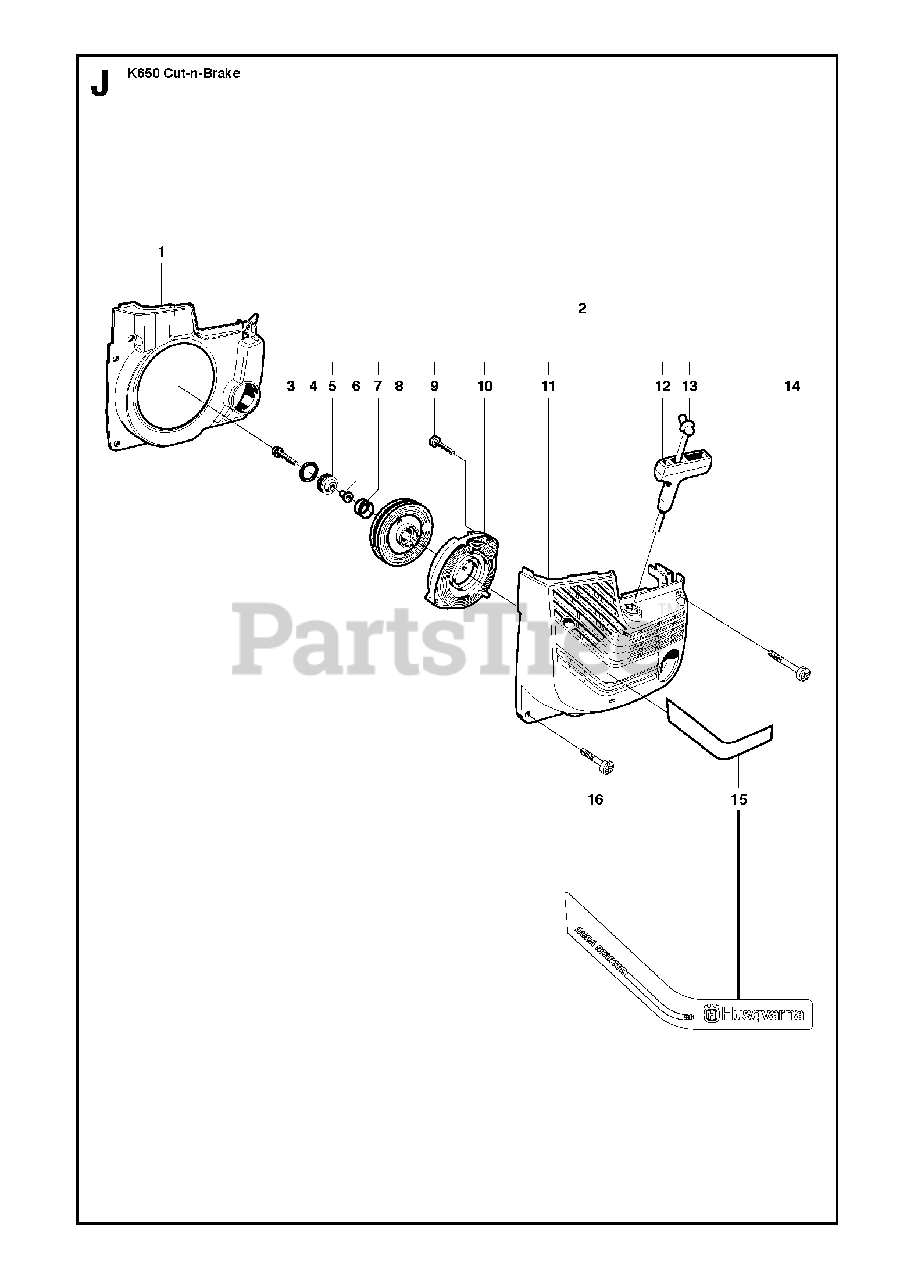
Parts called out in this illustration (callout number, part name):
1	STARTER HANDLE
4	SCREW IHSCFT
6	GROMMET
7	SPACING SLEEVE
8	COMPRESSION SPRING
9	STARTER PULLEY
10	SCREW CCRPANT
11	RECOIL SPRING
14	SCREW CCRPANMO
16	SCREW CCRPANMO
